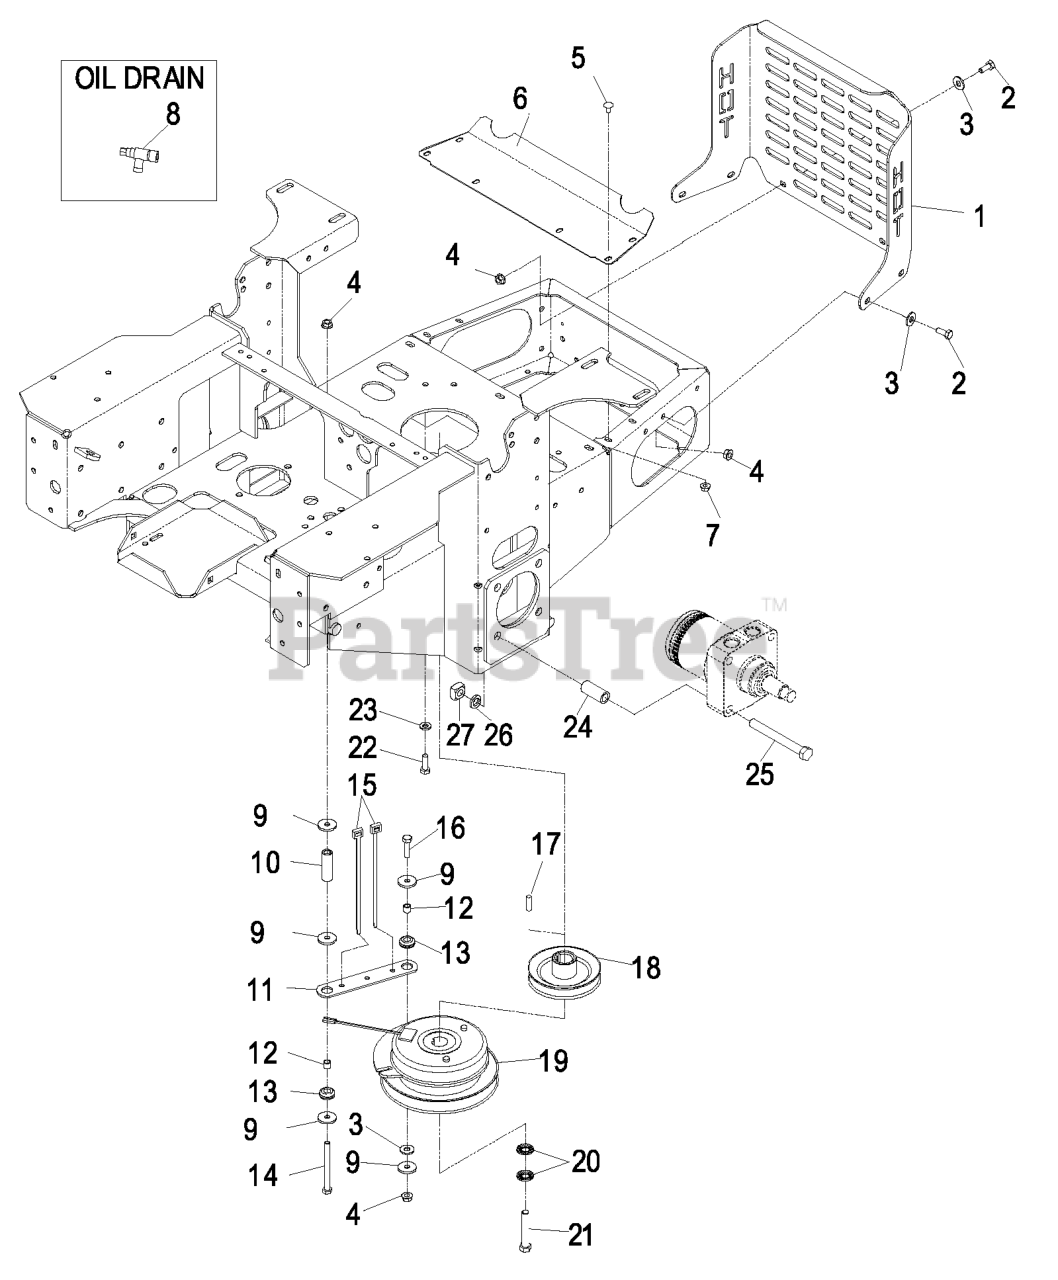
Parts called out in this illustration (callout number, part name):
1	BUMPER-REAR
2	SCREW-HH
3	WASHER-FLAT
5	SCREW-CARR
6	DEFLECTOR-SHORT
8	VALVE-DRAIN, OIL
11	STRAP-CLUTCH, BRAKE
13	GROMMET
14	SCREW-HH
15	TIE-PLASTIC
16	SCREW-HH
20	WASHER-SPRING
21	SCREW-HH
22	SCREW-HH
23	WASHER-SPRING
24	SPACER-MOTOR, WHEEL
25	SCREW-HH
26	WASHER-LOCK
